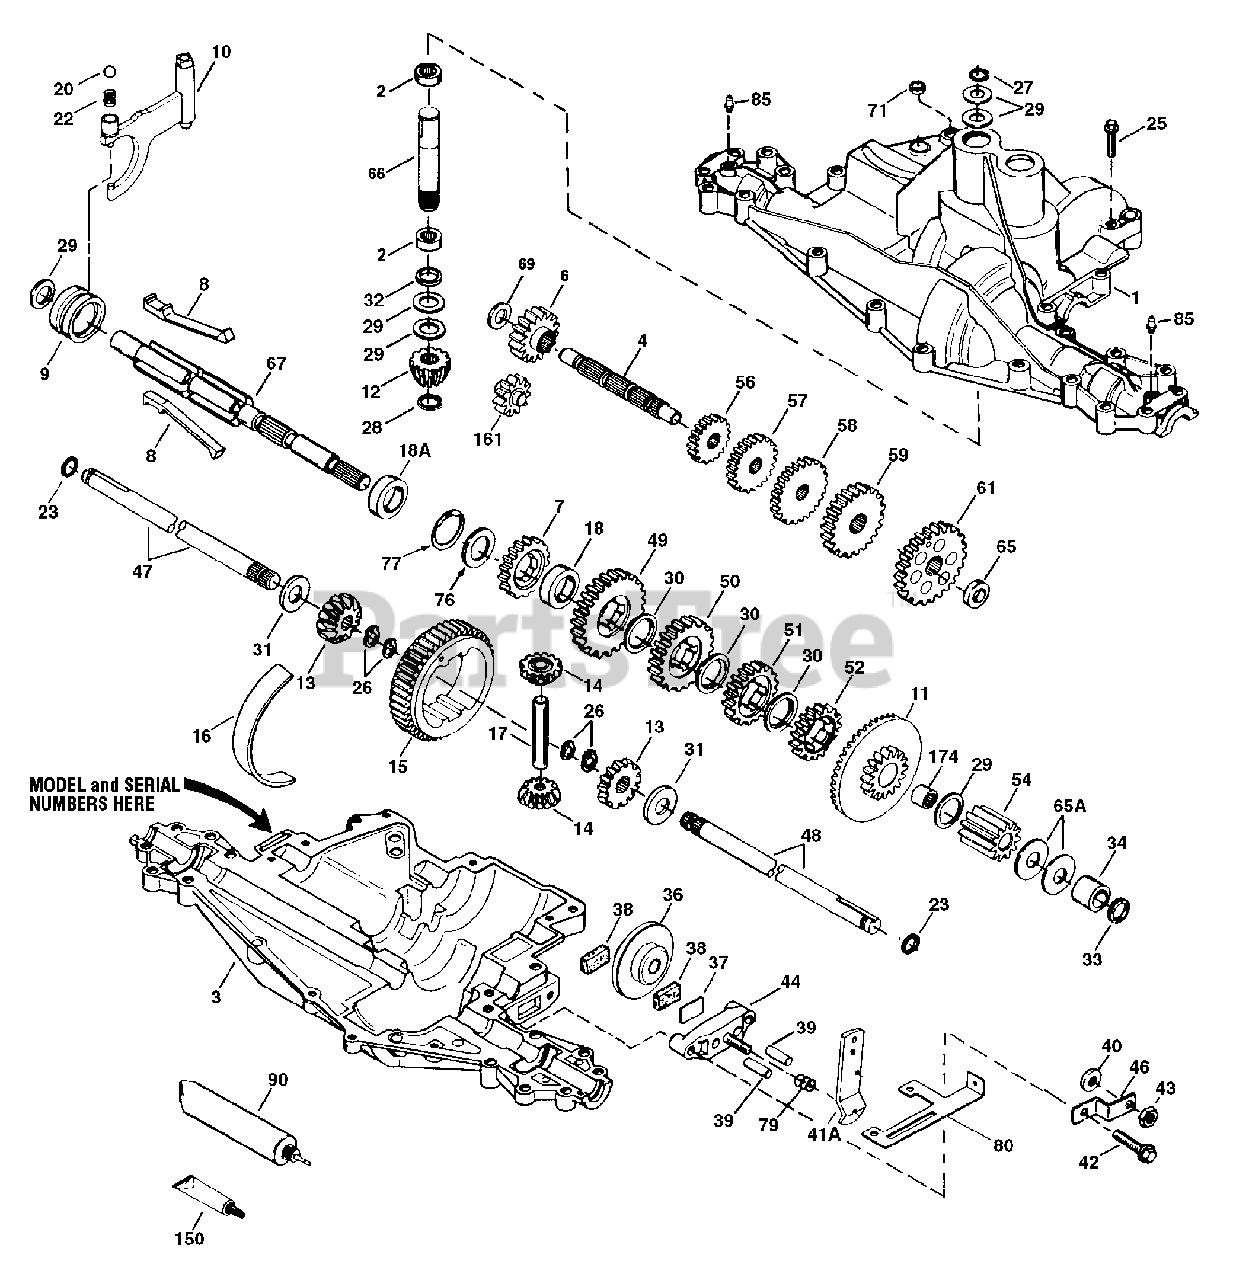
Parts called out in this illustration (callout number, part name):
1	Transaxle Cover
2	Needle Bearing
3	Transaxle Case
4	Countershaft
6	Spur Gear (16 teeth)
7	Spur Gear (22 teeth)
8	Shift Key
9	Shift Collar
10	Shift Rod & Fork
11	Bevel Gear & Bearing
12	Bevel Pinion (14 teeth)
13	Bevel Gear (16 teeth)
14	Differential Pinion
15	Ring Gear
16	Bearing Strip
18	Neutral Spacer
18A	Neutral Spacer
20	Ball, 5/16" dia.
25	Screw, 1/4-20 x 1-1/4"
26	Retaining Ring
27	Retaining Ring
28	Retaining Ring
36	Brake Disk
37	Brake Pad Plate
38	Brake Pad
40	Washer
41	Brake Lever
42	Screw, 1/4-20 x 1-1/4"
43	Locknut, 5/16-24
44	Brake Pad Holder
46	Brake Lever Bracket
47	Axle (16-1/4" long)
48	Axle (11" long)
49	Spur Gear (30 teeth)
50	Spur Gear (25 teeth)
51	Spur Gear (22 teeth)
52	Spur Gear (19 teeth)
54	Spur Gear (11 teeth)
56	Spur Gear (20 teeth)
57	Spur Gear (25 teeth)
58	Spur Gear (28 teeth)
59	Spur Gear (30 teeth)
61	Spur Gear (34 teeth)
65	Washer
66	Input Shaft
67	Shifter & Brake Shaft
69	Washer
71	Square Cut Ring
77	Inverted Retaining Ring
80	Brake Bracket
85	Lubrication Fitting
90	Grease
150	Gasket Eliminator
161	Reverse Idler
174	Needle Bearing
